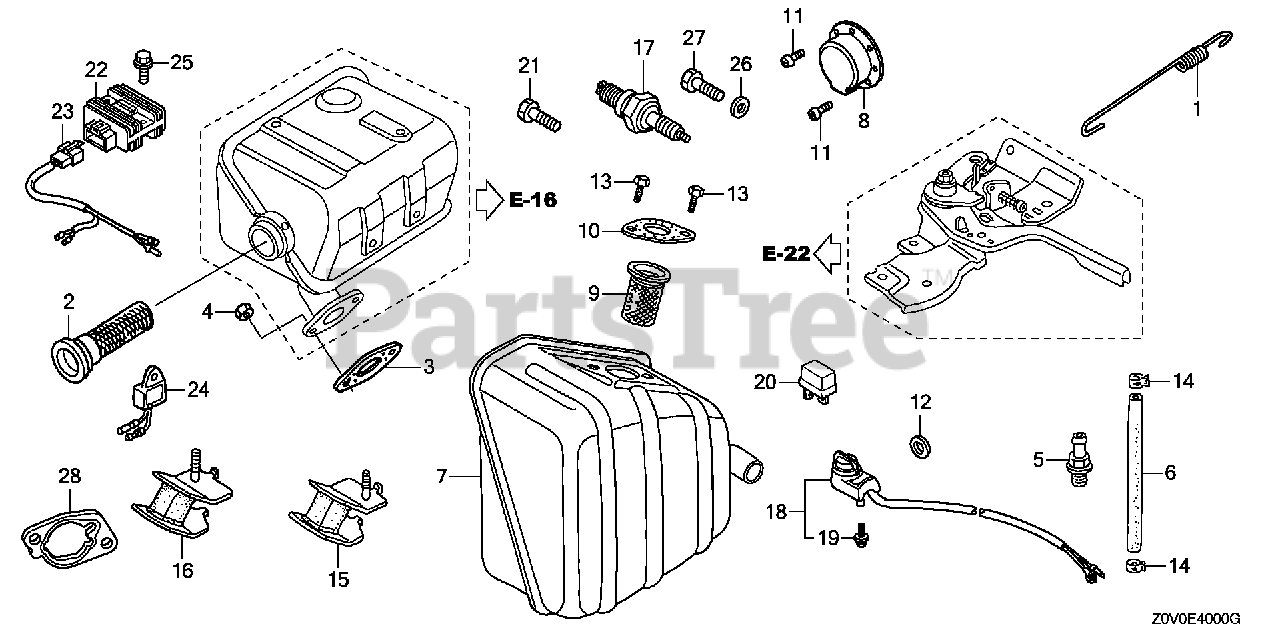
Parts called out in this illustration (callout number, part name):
5	JOINT, DRAIN
6	TUBE, DRAIN
8	CAP, MUFFLER
11	SCREW, TAPPING (4X6)
12	WASHER, DRAIN PLUG (10.2MM)
14	CLAMP, TUBE (D12)
